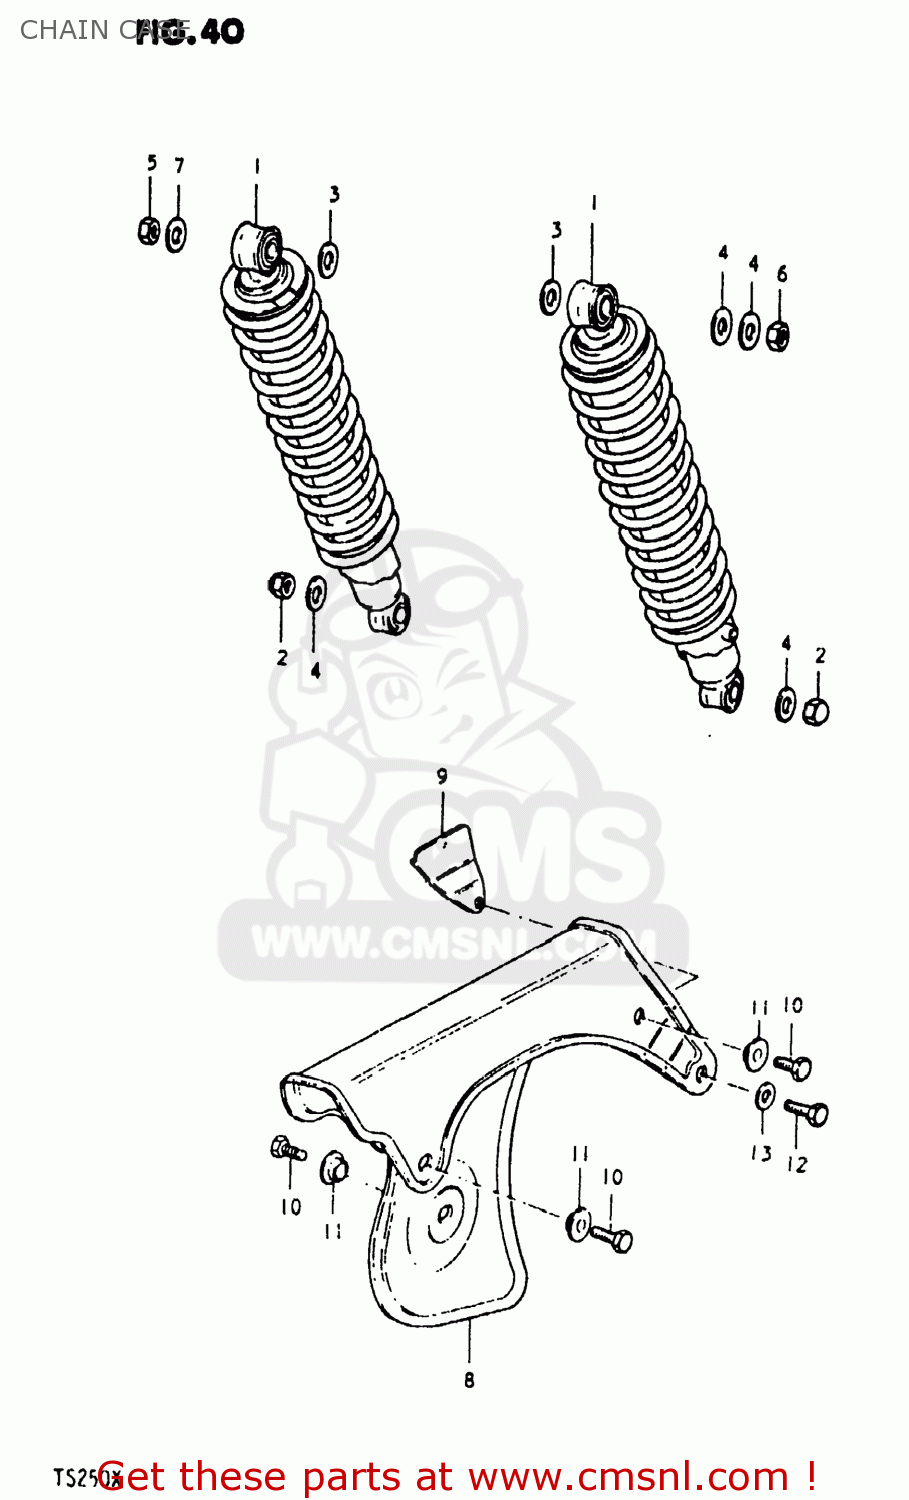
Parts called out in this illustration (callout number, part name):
1	ABSORBER ASSEMBLY,REAR SHOCK
2	NUT, LOWER LH
3	WASHER
4	WASHER
5	NUT
6	NUT
7	WASHER (12.5X24X3.2)
8	CASE,CHAIN
9	REINFORCEMENT,CHAIN CASE
10	BOLT(6X8)
11	WASHER
12	BOLT
13	WASHER
